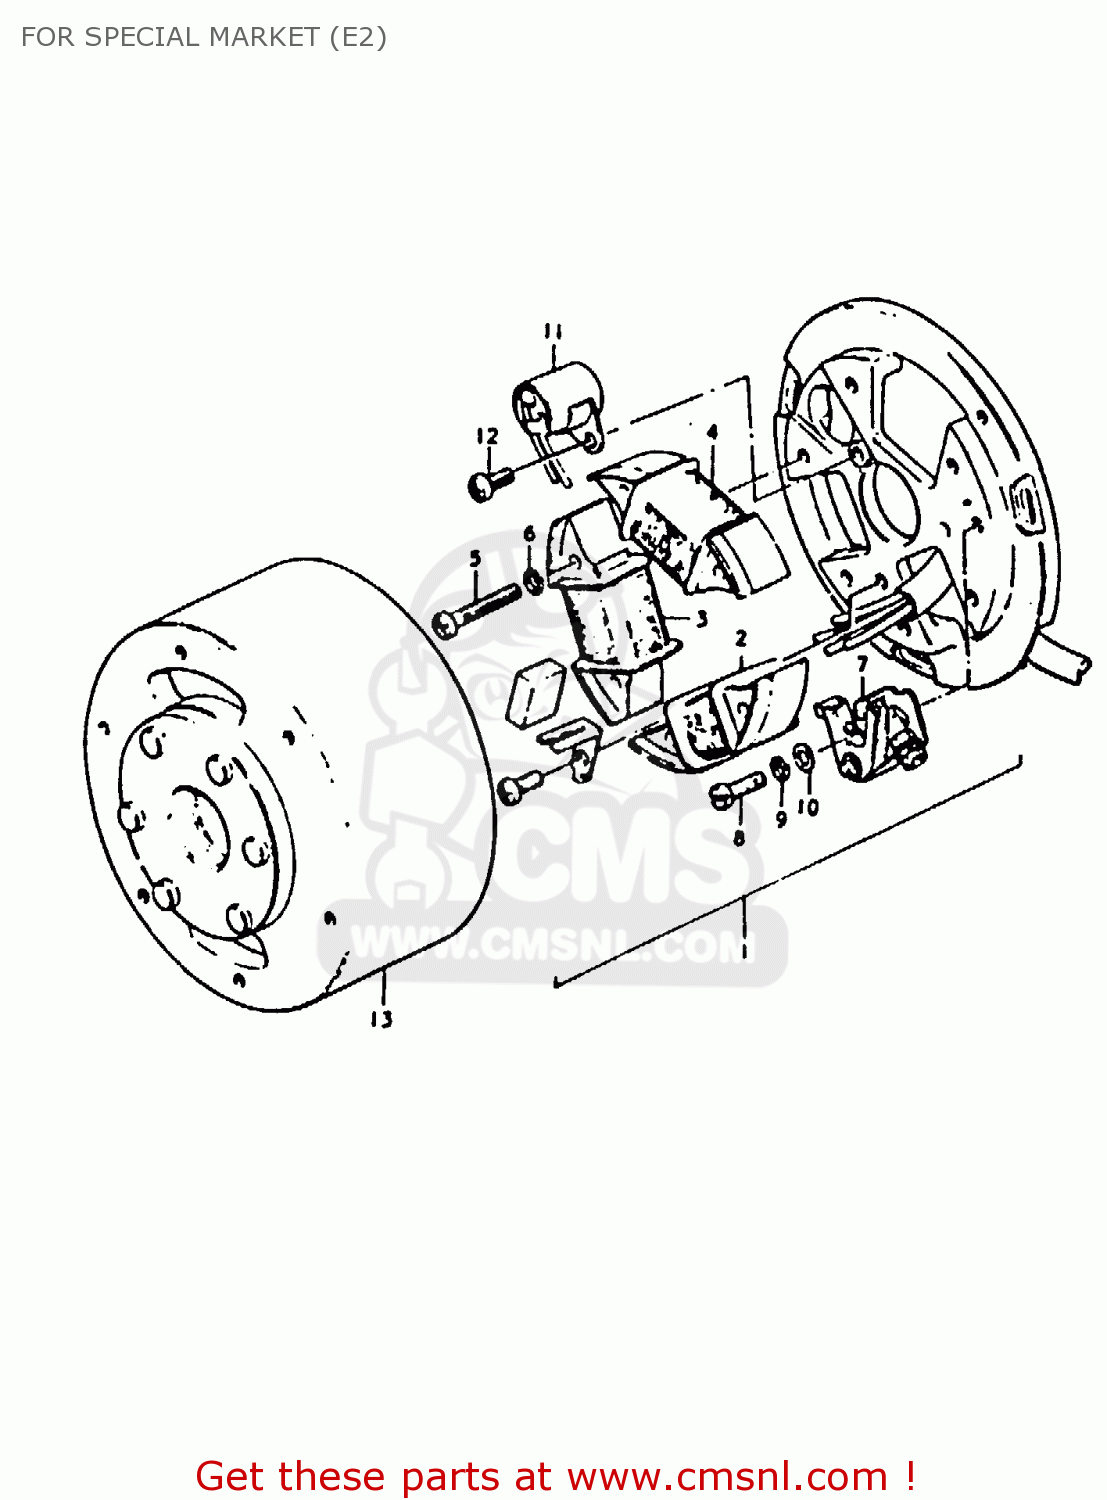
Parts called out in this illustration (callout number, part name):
1	CAP,MAGNETO INSPECTION
2	EMBLEM,CONTACT BREAKER CAP
4	SCREW
7	SCREW
8	SCREW
9	CAP,MAGNETO COVER SEAL
10	PIN
12	SCREW (6X45)
13	SCREW
15	GASKET,CLUTCH COVER (MCA)
16	SCREW 6X70
17	SCREW
18	SCREW (6X45)
19	SCREW (6X35)
20	SCREW
23	SCREW(6X10)
24	GASKET(6.2X11X1) (NAS)
25	CAP,CARBURETOR INSPECTION
26	EMBLEM,CONTACT BREAKER CAP
27	GASKET (MCA)
28	SCREW
29	Plug
30	GROMMET
31	HOSE
32	GROMMET
33	HOSE
34	COVER,CARBURETOR,TOP
35	SCREW
